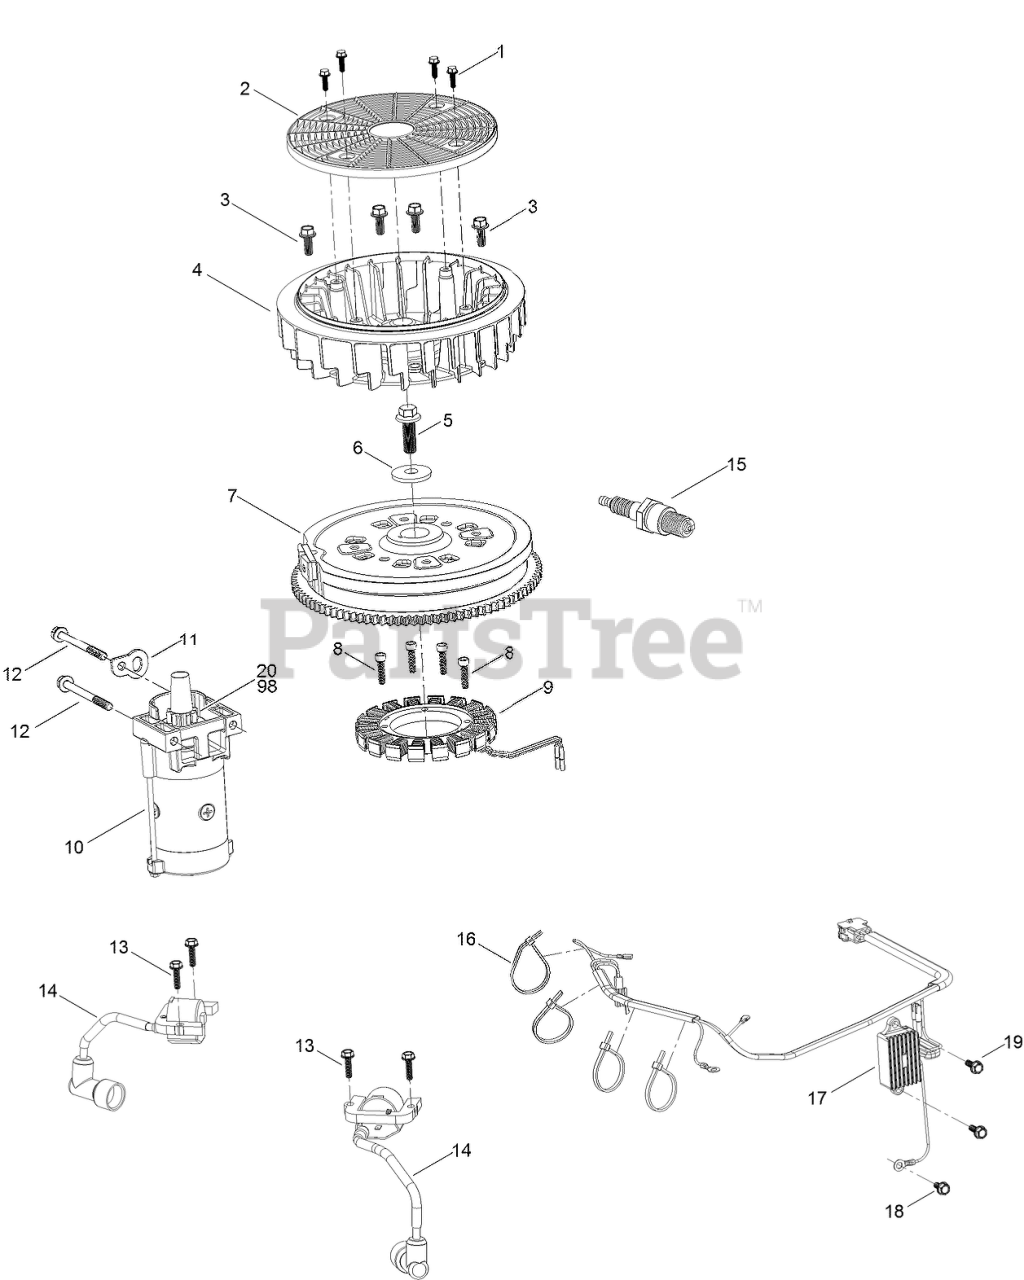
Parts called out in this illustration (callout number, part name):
1	SCREW-HWH
2	SCREEN-ROTATING
3	SCREW-HWH
4	FAN-COOLING
5	SCREW-HWH
6	WASHER-FLAT
7	FLYWHEEL
8	SCREW-HSH
9	ALTERNATOR
10	MOTOR-STARTER
11	BRACKET-LIFT
12	SCREW-HHF
13	BOLT-FLANGE
14	IGNITION COIL ASM
15	SPARK PLUG
16	TIE-ZIP
17	REGULATOR-VOLTAGE W/HARNESS
18	SCREW-HHF
19	SCREW-HHF
20	PINION-STARTER
98	STARTER REPAIR KIT
